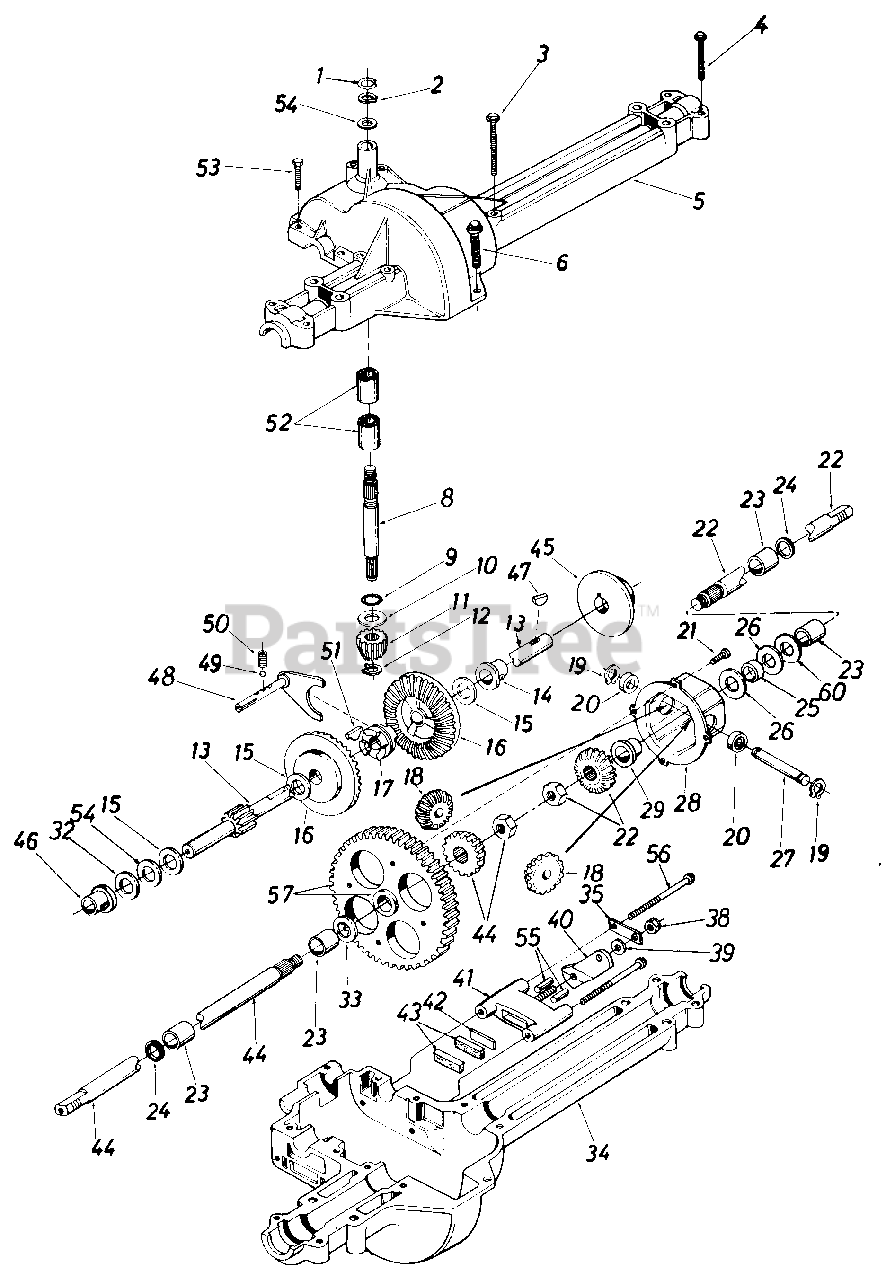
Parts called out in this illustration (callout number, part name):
1	Wire Ring
2	Retaining-Ring
3	Hex Bolt 1/4-20 x 1.75" Lg.
4	Hex Tap Scr. 1/4-20 x 1.25" Lg.
5	Upper Housing
6	Hex TT-Tap Scr. 1/4-20 x .75" Lg.
8	Input Shaft
9	Square Seal 5/8" I.D.
10	Thrust Washer 5/8" I.D. x 1.25 O.D.
11	Pinion Input 14T
12	Retaining Ring
13	Drive Shaft
14	Flange Brg. 5/8" I.D. x 3/4" Lg.*
15	Fl-Wash. 5/8" I.D. x 1.25"
16	Bevel Gear 42T
17	Clutch Collar
18	Miter Gear 15T (H.D.)
19	Snap Ring
20	Thrust Bearing
21	Pan Head Scr. 1/4-20 x .50" Lg. w/Patch
22	Axle R.H. Ass'y.
23	Sleeve Bearing 3/4" I.D. x 1.0" Lg.
24	Oil Seal 3/4" I.D.
25	Axle Spacer
26	Fl-Wash. 760" I.D. x 1.5" O.D.
27	Cross Shaft
28	Differential Cam Ass'y.
32	Washer
33	Fl-Wash. 760" I.D. x 1.5" O.D.
34	Lower Housing
35	Anti-Rotation Brkt.
38	Hex Nut 5/16-24 Thd.
39	Fl-Wash. .844" I.D. x .875" O.D.
40	Actuating Arm
41	Brake Yoke
42	Puck Plate
43	Brake Puck
44	Axle L.H. Ass'y.
45	Brake Disc
46	Flange Bearing 5/8" I.D. x 15/16" Lg.
47	Woodruff Key 3/16 x 5/8 HT
48	Shift Fork Ass'y.
49	Ball Detent .250" Dia.
50	Spring Detent
51	#9 Hi-Pro Key 3/16" x 3/4" Dia. HT
52	Needle Brg. 5/8" I.D. x 1/2" Lg.
53	Hex Bolt 1/4-20 x 1.00" Lg
54	Fl-Wash. 5/8" I.D. x l" O.D. x .020 Thk.
55	Actuating Pin 5/16" Dia.
56	Hex Wash Hd. Self-Tap Scr. 1/4-20 Thd.
57	Differential Gear 72T Ass'y. w/ Bearing
60	Washer
